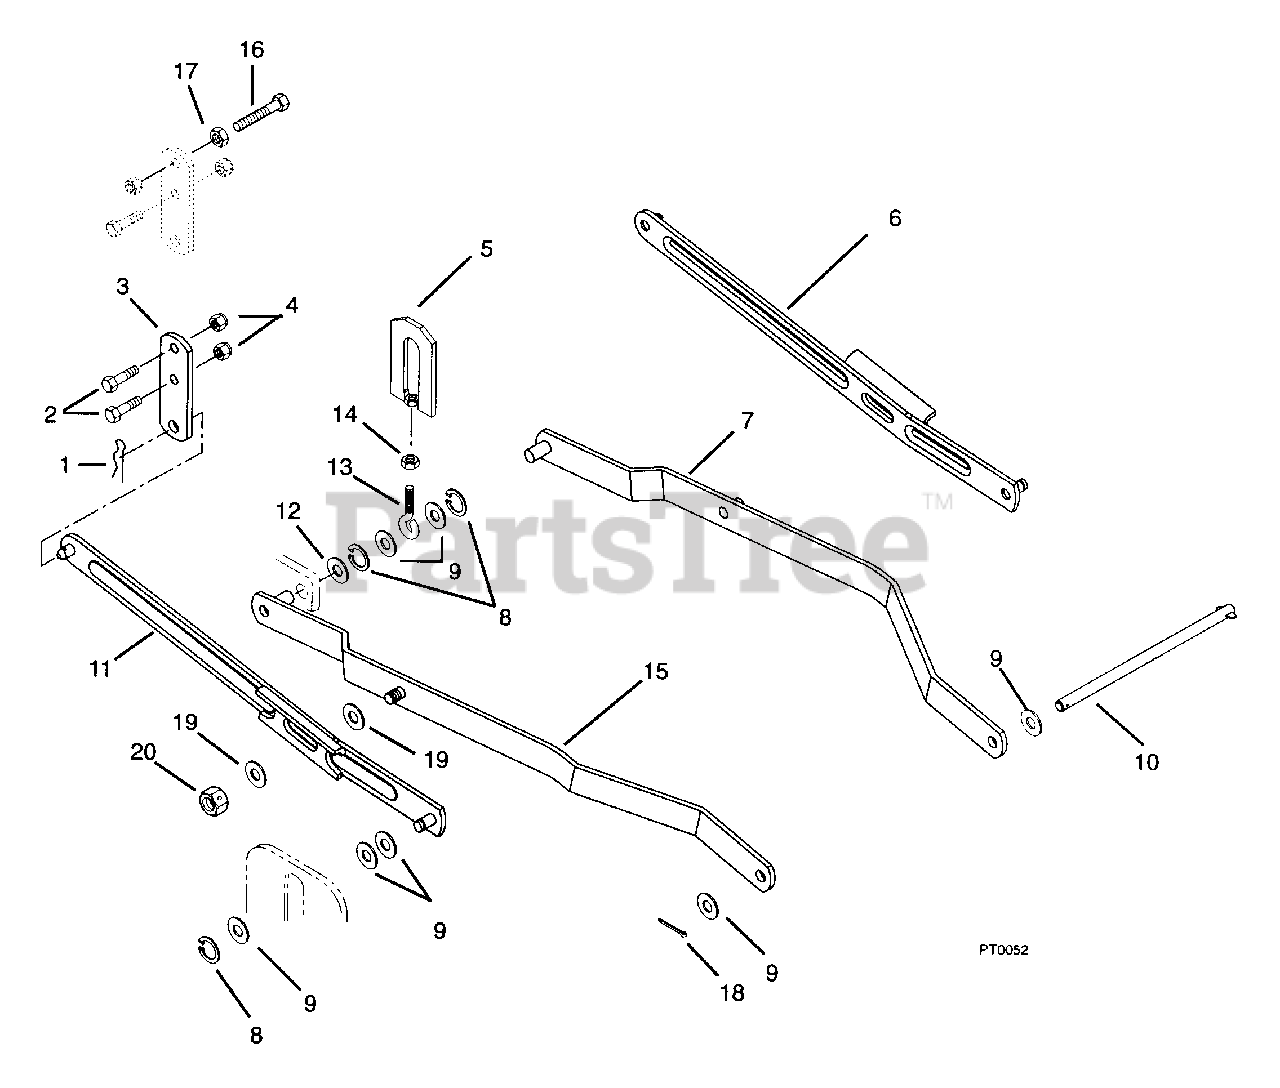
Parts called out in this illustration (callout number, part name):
1	PIN-HAIR EXT .12X.31X2.37 PL
2	BLT-HEX .38-16X.75 PL GR5
3	HANGER BRACKET
4	NUT-LK TOP .375-16 GR C YWZC
5	LINK, ADJUSTMENT
6	REAR HANGER LH
7	L.H. LIFT ARM
8	RG-RTNG-EXT .500X.050 (SNAP)
9	WSHR-FL-STL .531X1.062X.095 PL
11	REAR HANGER RH
12	WSHR-FL-STL .531X1.250X.100 PL
14	NUT-JAM .375-16 PL
15	R.H. LIFT ARM
16	BLT-HEX .38-16X1.75 PL GR5
17	NUT-HEX .375-16
18	PIN-COTR .12X1.0 PL
19	WSHR-FL-STL.656X1.312X.095 PL
20	NUT-LK-CTR .625-11 TYP N
